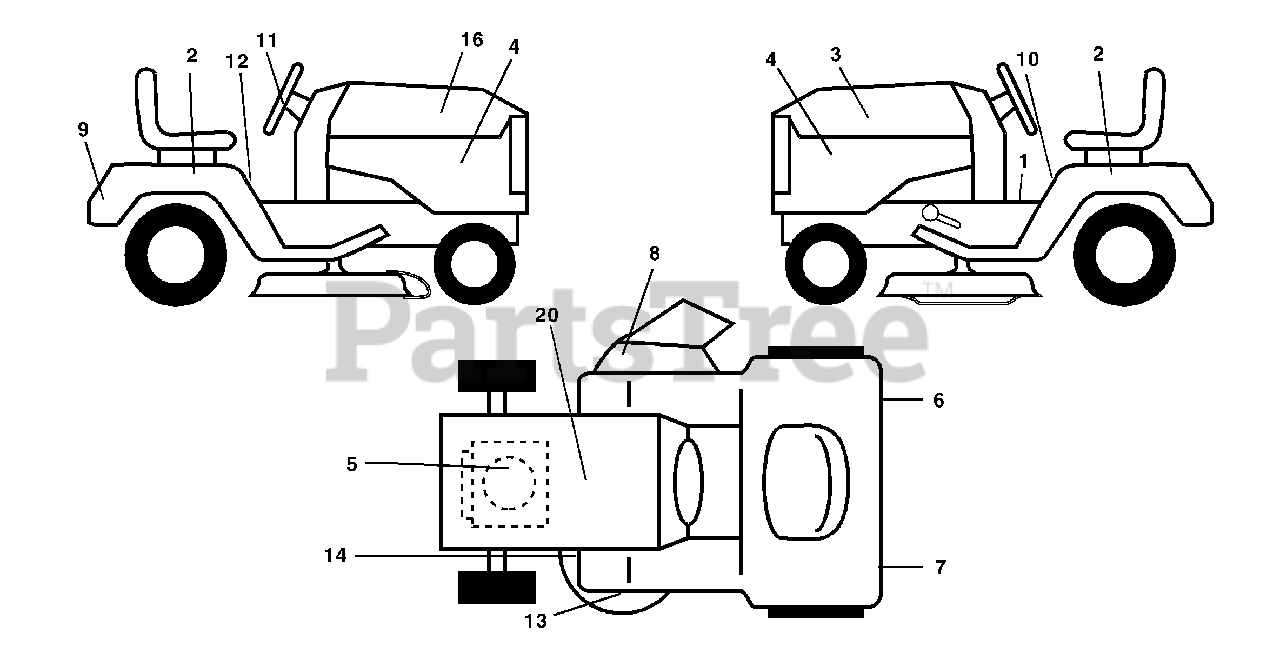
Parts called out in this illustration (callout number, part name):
1	Decal Dash
2	Decal Fender Auto
3	Decal Hood LH
4	Decal Side Panel
5	Decal HP Engine
6	Decal Reflector Rh
7	Decal Reflector Lh
8	Decal Warning Mower
9	Decal Fender Logo
10	Decal Fender Danger E/F
11	Decal Ins Strg Whl
12	Decal Fender Oper Cruise
13	Decal Deck Caution
14	Decal V-Belt Schematic
16	Decal Hood Rh
20	Decal Bat Dan/Psn
